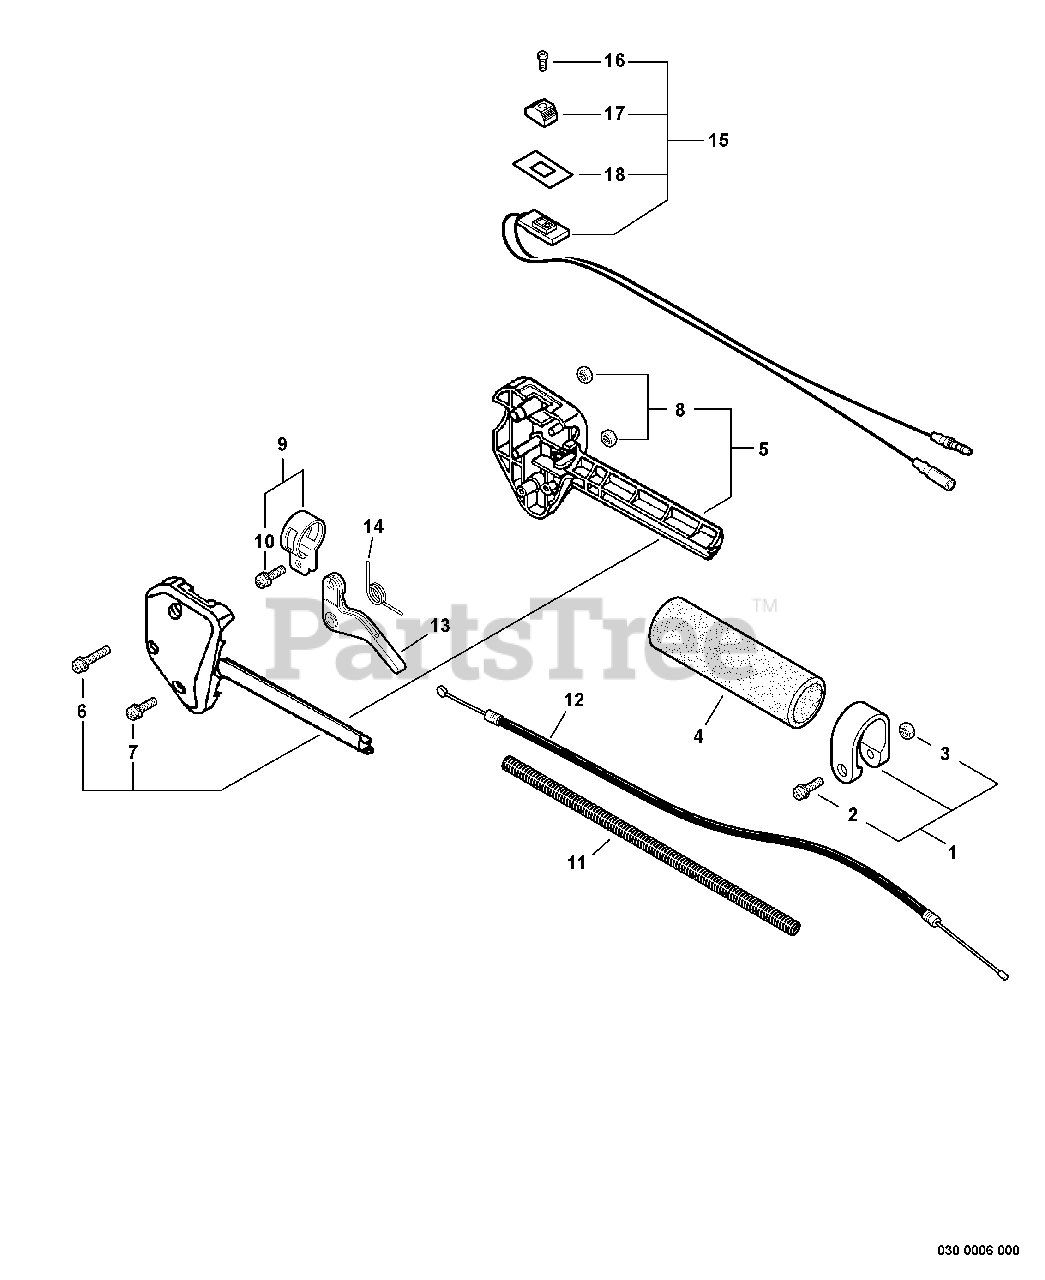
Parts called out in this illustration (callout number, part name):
1	CLAMP KIT
2	SCREW - 5X28
4	GRIP, HANDLE
5	CONTROL HANDLE KIT
6	SCREW - 5X35
7	SCREW - 5X25
9	CLAMP KIT
10	SCREW - 5X14
11	TUBE, PROTECTIVE - CORRUGATED
12	CABLE, THROTTLE
13	TRIGGER, THROTTLE
14	SPRING, TRIGGER
15	IGNITION SWITCH ASSY
16	SCREW - 3X10
17	KNOB, SWITCH - ORANGE
18	COVER, SWITCH - STOP
